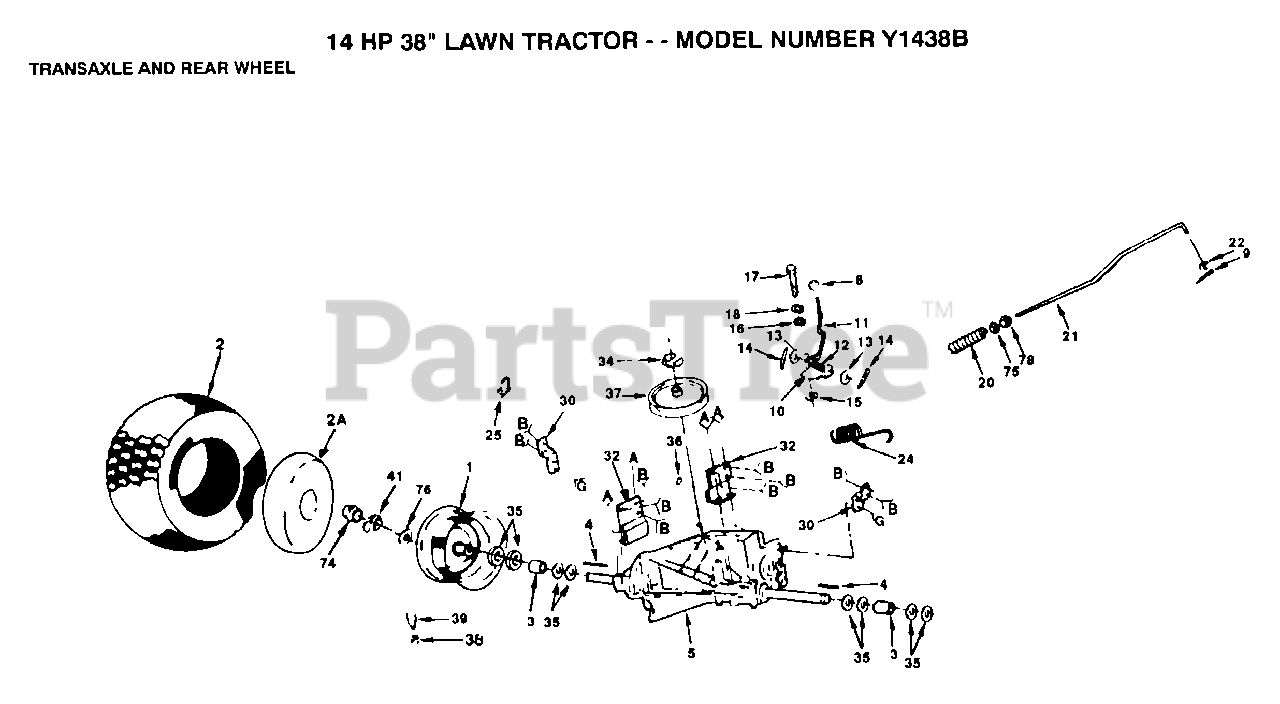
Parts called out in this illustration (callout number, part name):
2A	TUBE.18X9.5-8
3	SPACER LT
4	SQUARE KEY
8	KNOB.DUCKHEAD.1/2
9	COTTER PIN
10	PLATE SHIFT LT
11	ROD SHIFTER
12	SPRING LT
13	WASHER
14	PIN COTTER 1/8
15	WASH-SHFT PLT LT
16	WASHER LT
18	LOCKWASHER
20	SPRING ROD LT
21	BRAKE ROD LT
22	WASHER
25	CLIP T
30	STRAP TORQUE
32	BRACKET LT
35	WASHER
37	PULLEY TRANS
38	VALVE CAP
39	VALVE STEM LT
41	E-RING LT
74	HUB CAP
75	NUT
76	WASHER
78	NUT
